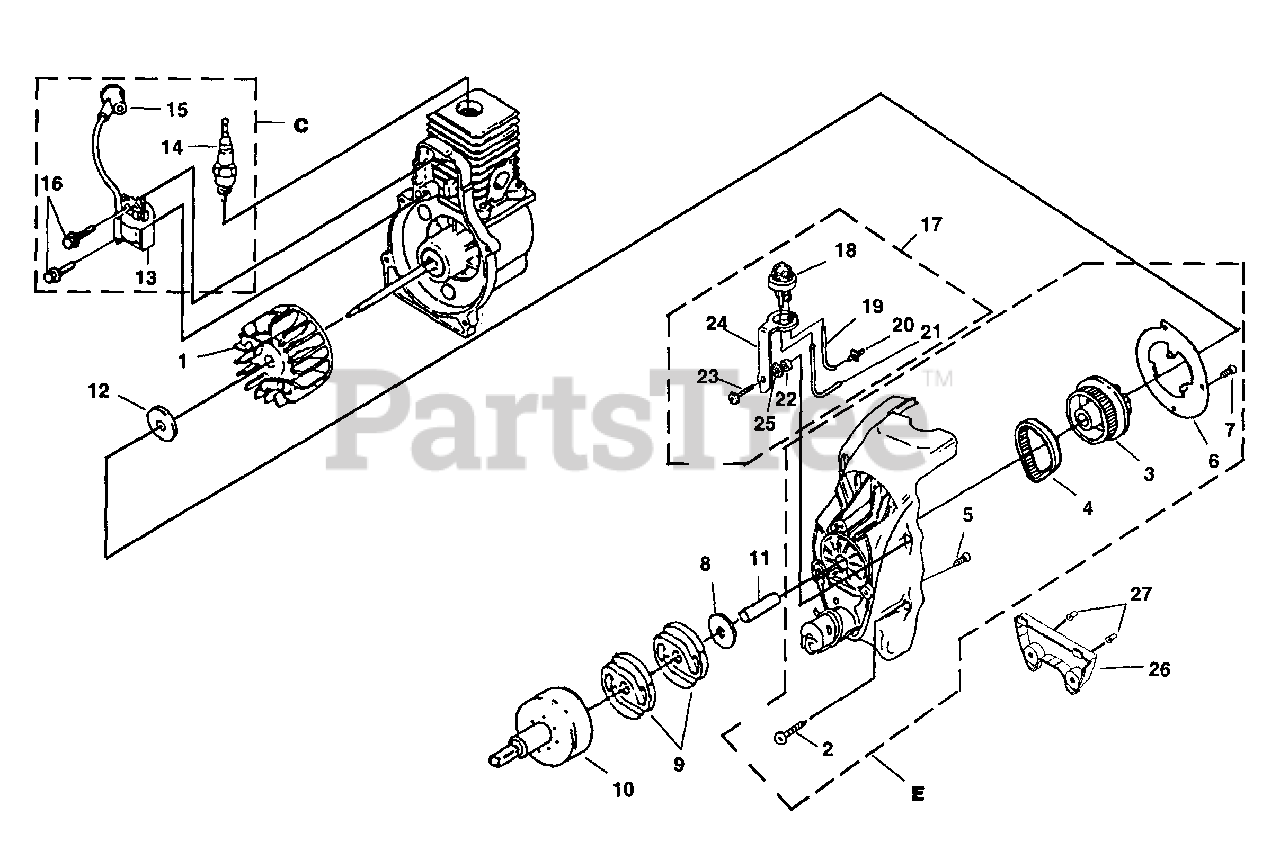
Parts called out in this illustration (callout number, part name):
1	ROTOR w/Starter Pawls
2	SCREW-Thread Form. (10-24 X 3/4")
3	PULLEY-Starter
4	BELT-Starter
5	SCREW-Thread Forming (8-32 X 1")
7	SCREW-Plastite (8-16 X 1/2")
8	WASHER-Flat
9	CLUTCH
10	CONNECTOR & DRUM
11	SPACER
13	MODULE-Ignition
14	SPARK PLUG
15	TERMINAL & COVER
16	SCREW-Taptite (8-32 x 1")
17	START ASSIST KIT
18	BULB-Primer
19	LINE-Fuel (2.0") (5,0 cm)
20	FITTING-Fuel Line
21	LINE-Fuel (2.5") (6,5 cm)
22	SPACER
23	SCREW - (10-24 x 1.00")
24	BRACKET
25	WASHER-External Lock
26	COVER ASSEMBLY
27	KNOB
E	COMPLETE STARTER ASSEMBLY
C	IGNITION KIT
